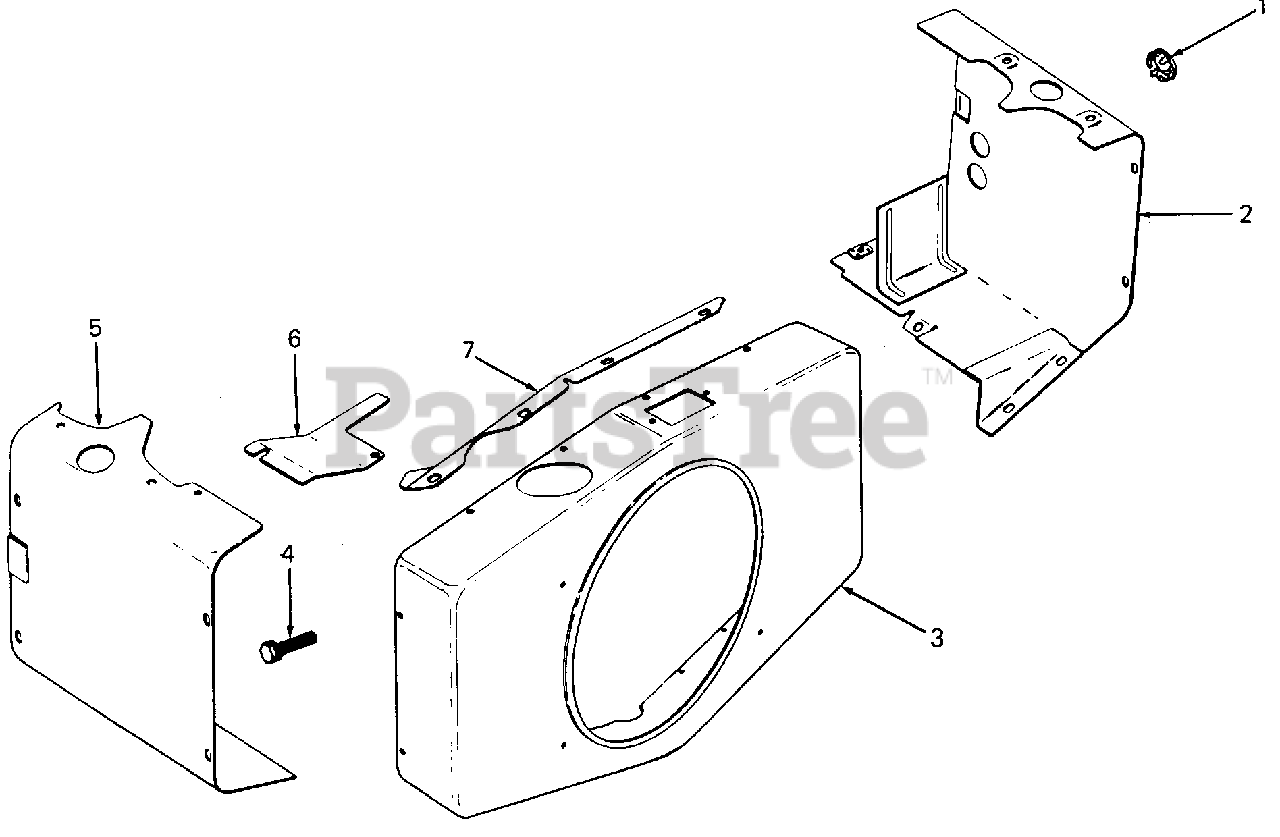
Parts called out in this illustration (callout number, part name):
1	Plug, Button
2	Baffle, #1 Cylinder Head
3	Blower Housing
4	Screw, Hex Wash Hd, 1/4-20 X 7/16
5	Baffle, #2 Cylinder Head
6	Baffle, #2 Cylinder Top
7	Support, Upper Housing
